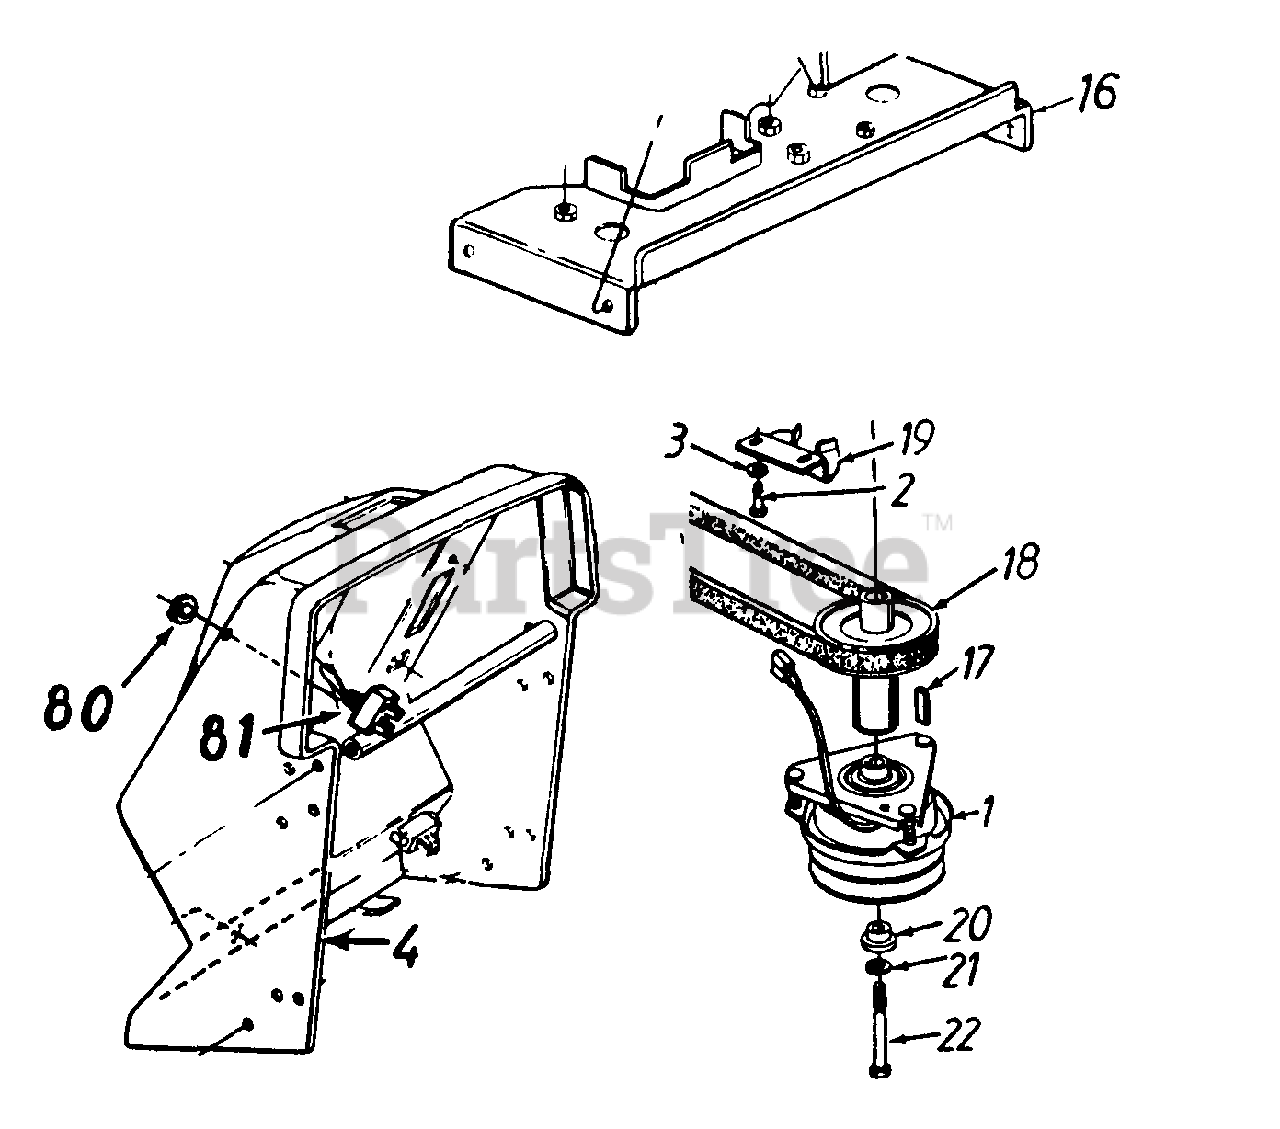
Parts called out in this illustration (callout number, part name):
1	Electric Clutch
2	Hex Bolt 5/16-18 x .75" Lg. (Gr. 5)
3	Bell-Wash. .345" I D. x .88"
16	Belt Guard Brkt. Ass'y.
17	Sq. Key 1/4" x 1 5" Lg.
18	Engine Pulley
21	L-Wash. 7/16" I.D.
22	Hex Bolt 7/16-20 x 3.25" Lg. (Gr. 5)
80	Hex Nut 1/2-27 Thd.
81	PTO Switch
